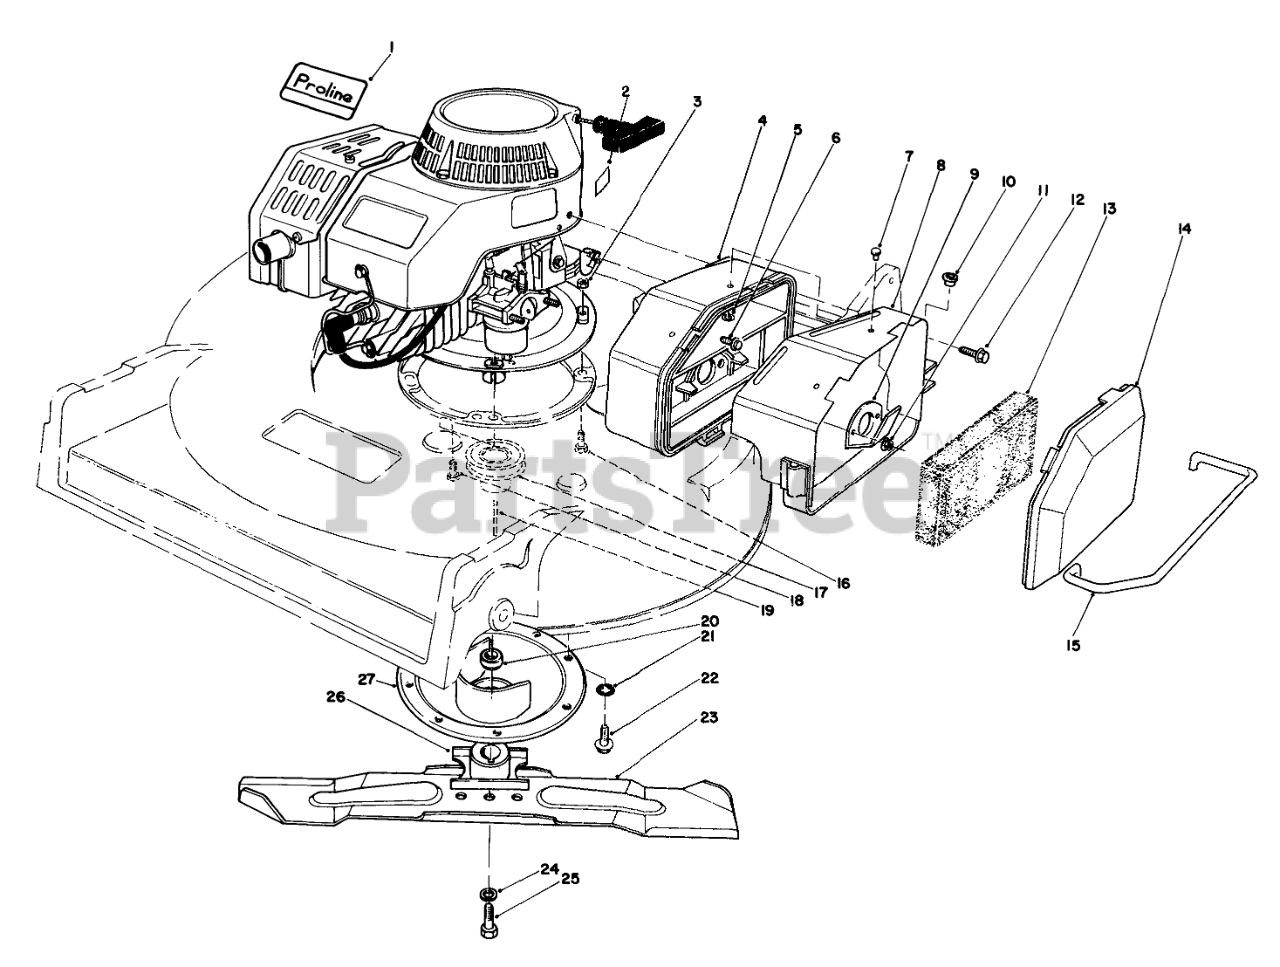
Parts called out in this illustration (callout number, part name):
1	DECAL - PROLINE
2	DECAL - FUEL
3	NUT-JAM
4	Air Cleaner Assembly (Incl. Ref. #5, 7, 8)
5	WASHER-FLAT
6	HEX FL HD M.6X1.0X25MM
7	RIVET-POP
8	AIR CLEANER COVER WA
9	SPIT BACK DEFLECTOR
10	5/16 ID BSHG
11	NUT-LOCK
12	SCREW-HHF
13	FILTER
14	AIR CLEANER COVER
15	AIR CLEANER GUARD
16	SCREW-HH
17	PULLEY-DRIVER
18	SCREW-HH
19	KEY-SQUARE
20	SPACER-BLADE RETAINER
21	WASHER-LOCK, INTERNAL
22	SCREW-HWHTF
23	BLADE-21in
24	WASHER-LOCK
25	SCREW-BLADE
26	RETAINER-BLADE
27	PROTECTOR-CRANKSHAFT
